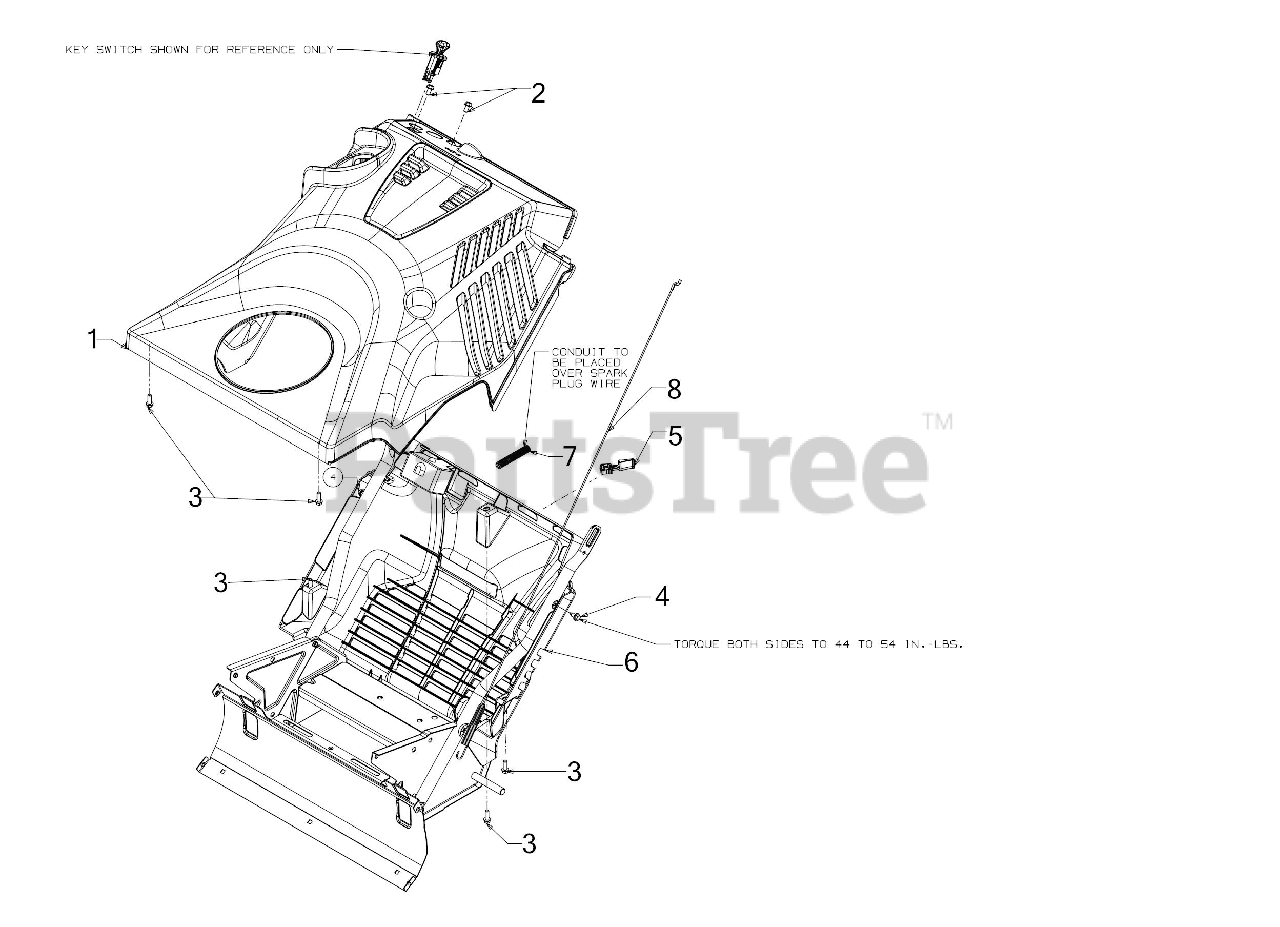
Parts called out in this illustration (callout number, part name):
1	COVER ASSEMBLY
2	HEX SCREW 1/4-15 x .50
3	SCREW 1/4-15 x .750
4	SCREW 1/4-20X.625
5	CHOKE EXTENION LEVER
6	BOTTOM COVER
7	CONVOLUTED CONDUIT
8	AUGER CLUTCH CABLE 37.05"
